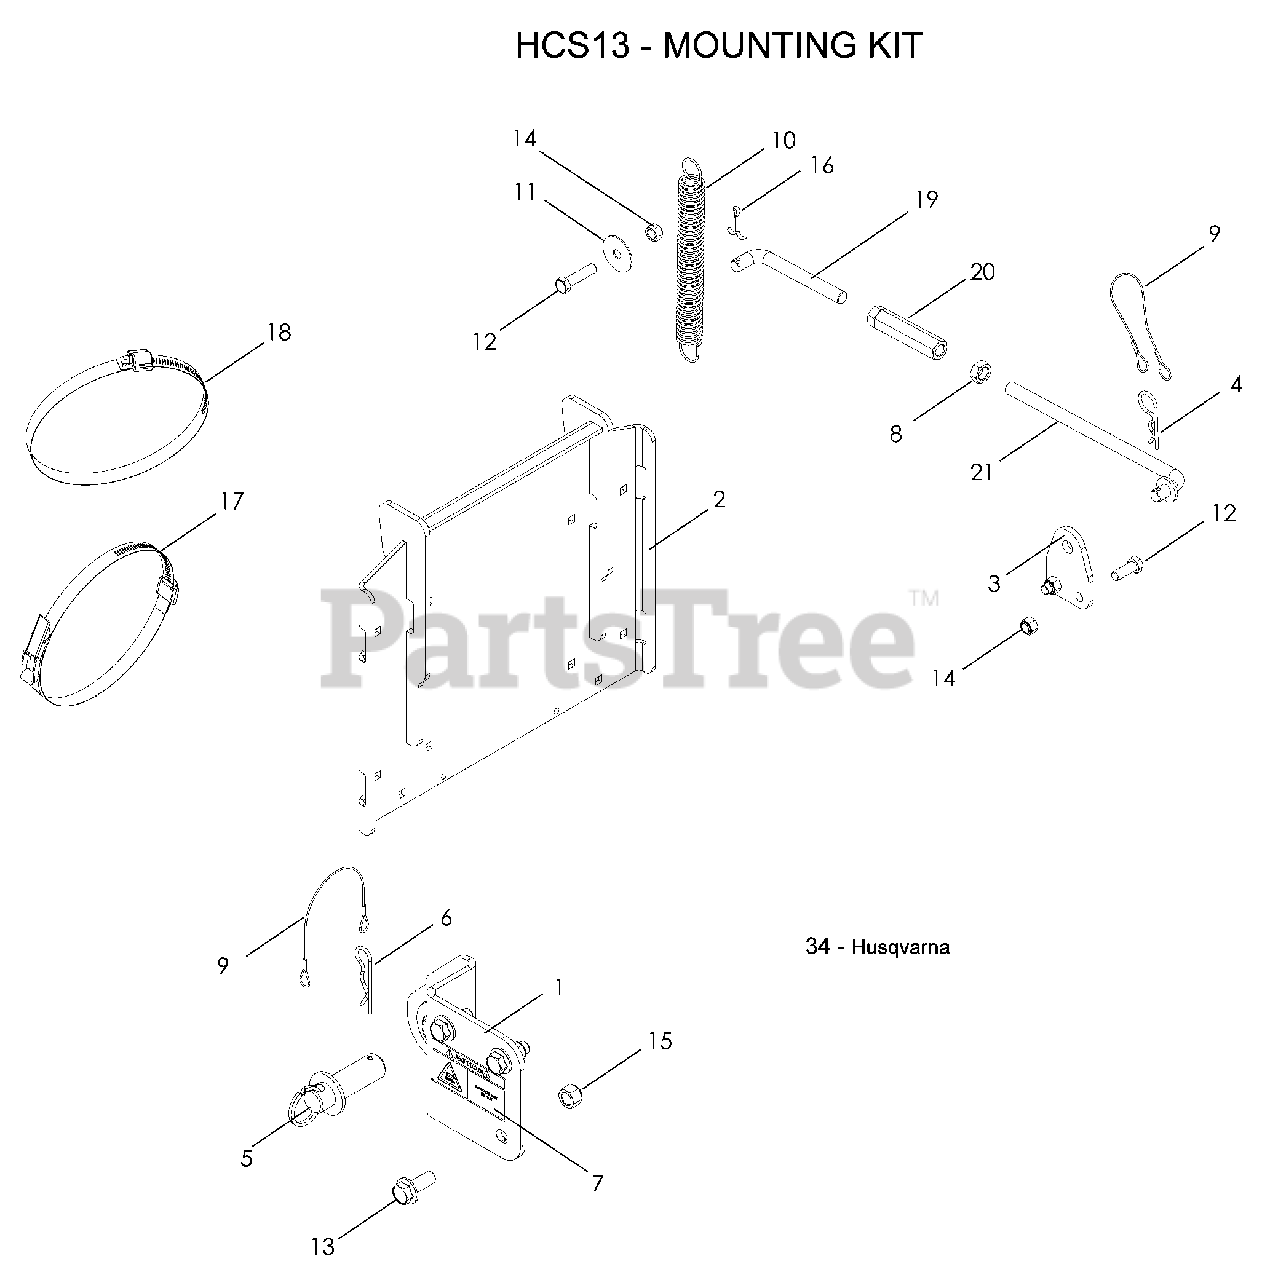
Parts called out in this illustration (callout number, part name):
1	BRACKET, RT W/DECAL
2	REAR GUARD
3	SUPPORT BRACKET
5	PIN, HITCH
7	DECAL, HOT SURFACE
8	NUT ½-20 HEX JAM
11	WASHER, FRICTION
12	HCS 3/8-16 x 1
13	HFCS ½-13 x 1¼ WHIZLK
14	NUT 3/8-16 HEX NYLOC
15	NUT ½-13 HEX NYLOC
16	PIN, COTTER 5/32 x 1¼
17	OVER CENTER BAND
18	HOSE CLAMP
19	SUPPORT LINKAGE, LH
20	TURNBUCKLE ½
21	SUPPORT LINKAGE
